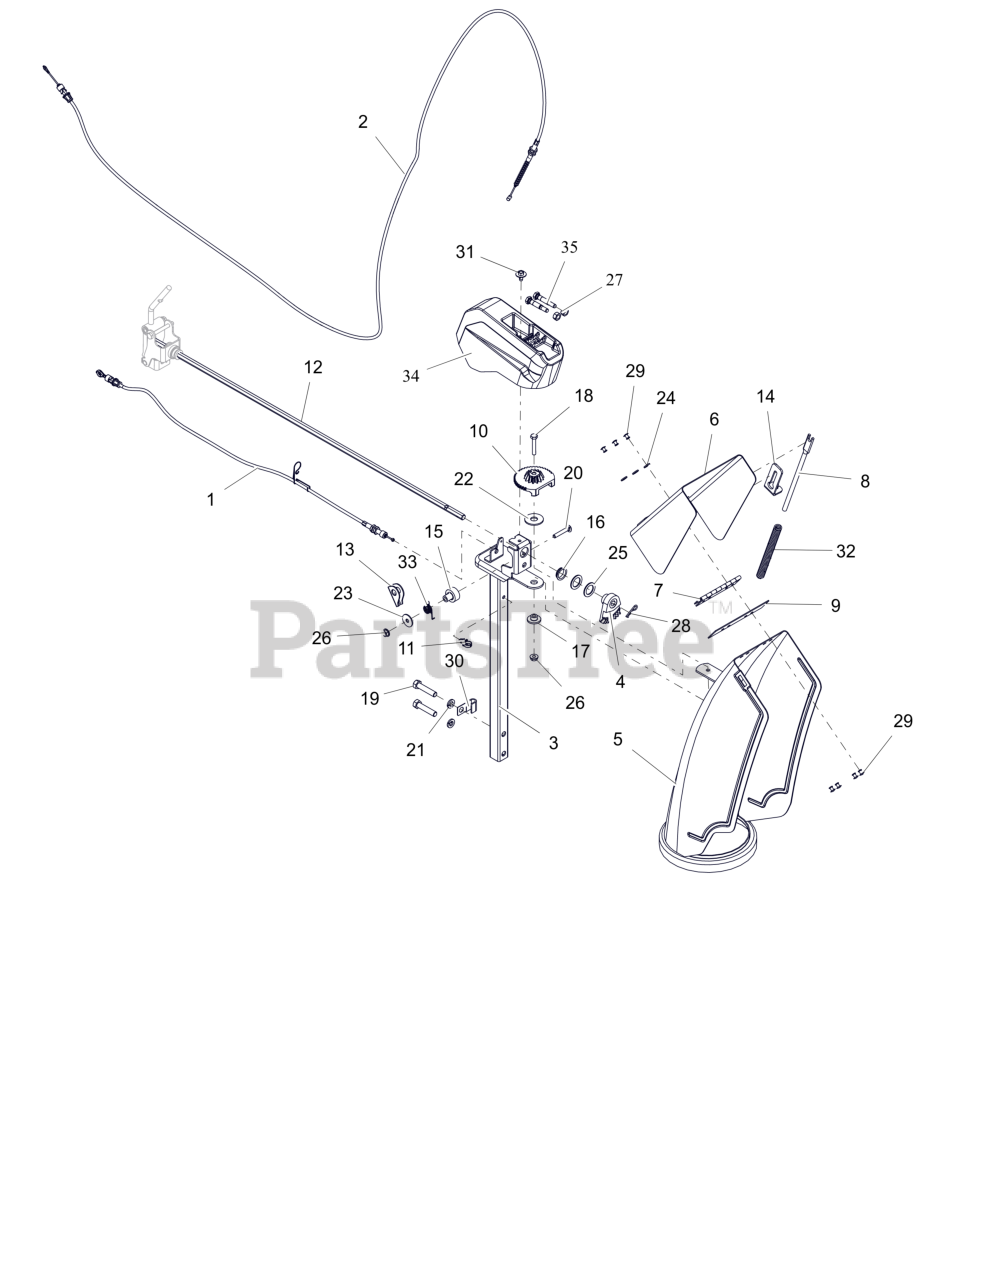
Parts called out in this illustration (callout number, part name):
1	CABLE, CHUTE LOCK, PRO
2	CABLE, DEFLECTOR - DELUXE
3	PEDESTAL, CHUTE - QUICK STICK
4	GEAR, CHUTE-ACTUATION
5	CHUTE,DISCHARGE,NOTCHED,QT
6	CAP, LARGE REMOTE W/DECAL
8	ROD, DEFLECTOR CAP
9	CAP SEAL 5.50
10	GEAR, CHUTE
11	CLIP, CABLE GUIDE
12	ROD, HEX - CHUTE ROTATION
13	ARM, LOCKING
14	BRACKET, ANCHOR-CHUTE CABLE
15	BUSHING, LOCK ARM
16	BUSHING, POLYLINER-.75 SNAPIN
17	BSHG-FLG .265X.477X.375X1.00
18	BLT, HEX .25-20X1.50 G5 ZCC
19	BLT, HEX .38-16X1.75 G5 ZCC
20	BLT, RHSN .25-20X1.50 G5 ZCC
21	WSHR,LK-REG .375X.094 ZCC
22	WSHR-FLT-NYL .515X1.375X.093
23	WSHR,FLT .281X1.000X.063 ZCC
24	WSHR,FLT .196X.500X.066 ZCC
25	WSHR, FLT .754X1.125X.062 ZCC
26	NUT-LK-CTR-FLG .25-20 ZC120
27	NUT,LK-CTR .31-18 GA ZCC
28	PIN, HAIR #213 .08X1.19 ZCC
29	RVT, POP .1875 ZCC
30	J-CLAMP
31	SCR, TAP .25-20X.50 LG HWH ZCC
32	SG-COMP .08X.40X6.50 14#/IN
33	SG-TORS
34	COVER, CHUTE PEDESTAL
35	SHEAR BOLT SERVICE ASSEMBLY
